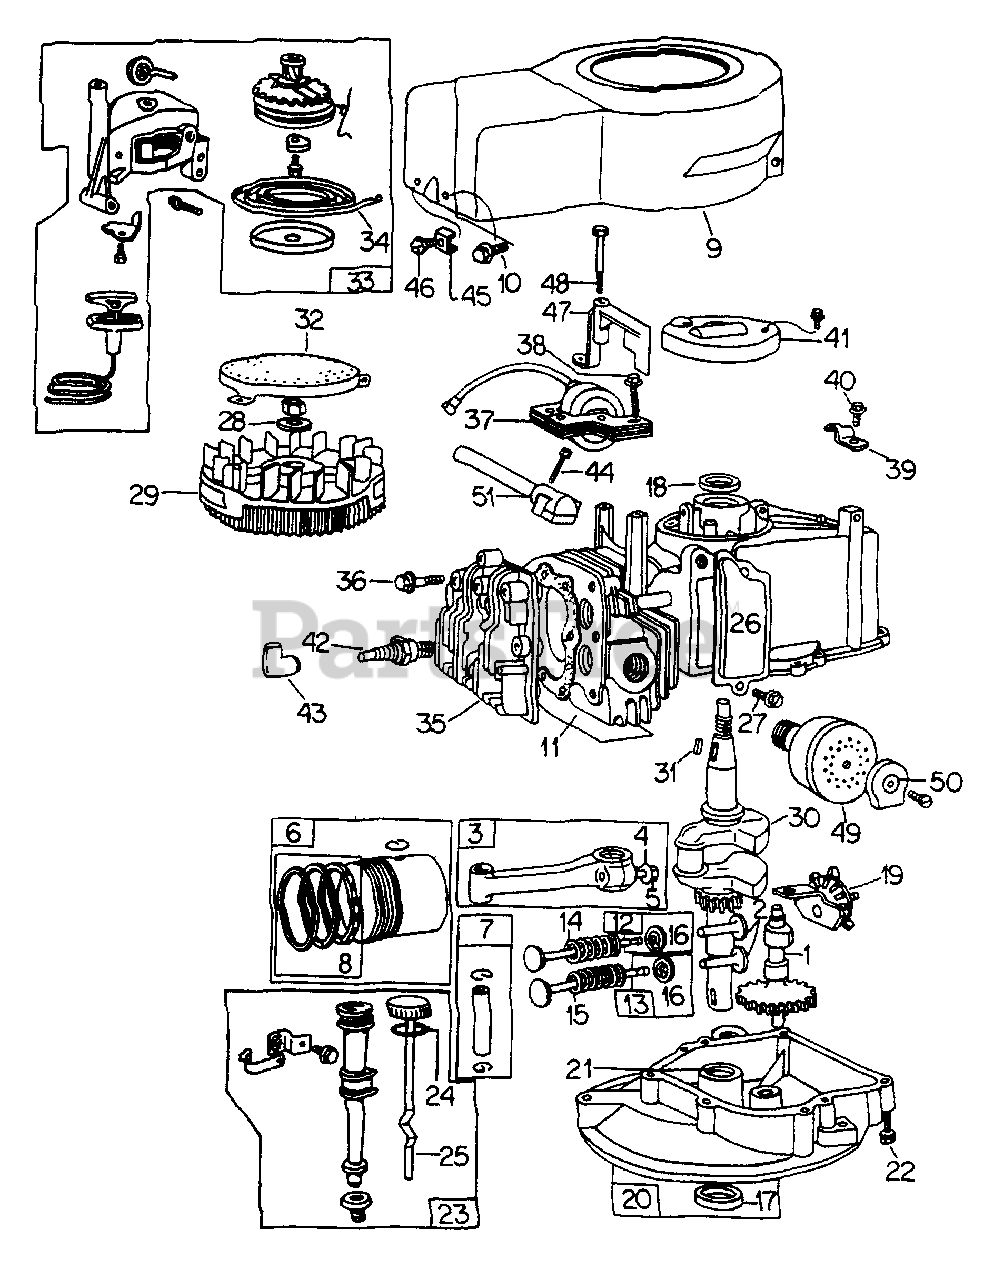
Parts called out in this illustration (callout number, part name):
2	TAPPET, VALVE
3	ROD ASSY, CONNECTING - STANDARD
4	LOCK, SCREW HEAD
5	SCREW, CONNECTING ROD
6	PISTON ASSY, STANDARD
7	PIN, PISTON AND RETAINER - STD
8	RING SET, PISTON - STANDARD
9	HOUSING, BLOWER
10	SCREW, BLOWER HOUSING
11	SHIELD, CYLINDER
12	VALVE, INTAKE
13	VALVE, EXHAUST
14	SPRING, INTAKE VALVE
15	SPRING, EXHAUST VALVE
16	RETAINER, VALVE SPRING
18	SEAL, OIL
19	SLINGER, OIL GEAR BRACKET
21	BUSHING, OIL SUMP
22	SCREW, SUMP MOUNTING
23	FILLER, OIL
24	RING, OIL FILLER CAP
26	BREATHER, VALVE CHAMBER
27	SCREW, BREATHER MOUNTING
28	WASHER, FLYWHEEL
31	KEY, FLYWHEEL
32	SCREEN, ROTATING
33	STARTER, VERTICAL PULL
34	SPRING, VERTICAL PULL STARTER
35	HEAD, CYLINDER
36	SCREW, CYLINDER HEAD
37	ARMATURE, MAGNETO
38	SCREW, ARMATURE MOUNTING
39	CLAMP, CONDENSER
40	SCREW, CONDENSER
41	COVER, BREAKER POINT
42	PLUG, SPARK (CHAMPION)
43	ELBOW, SPARK PLUG INSULATOR
44	SCREW, INTAKE ELBOW MOUNTING
45	CLAMP, CASING
46	SCREW W/LOCKWASHER, HEX-HD
47	BLADE, GOVERNOR
49	MUFFLER ASSY
50	DEFLECTOR, MUFFLER
51	TUBE, FUEL INTAKE
